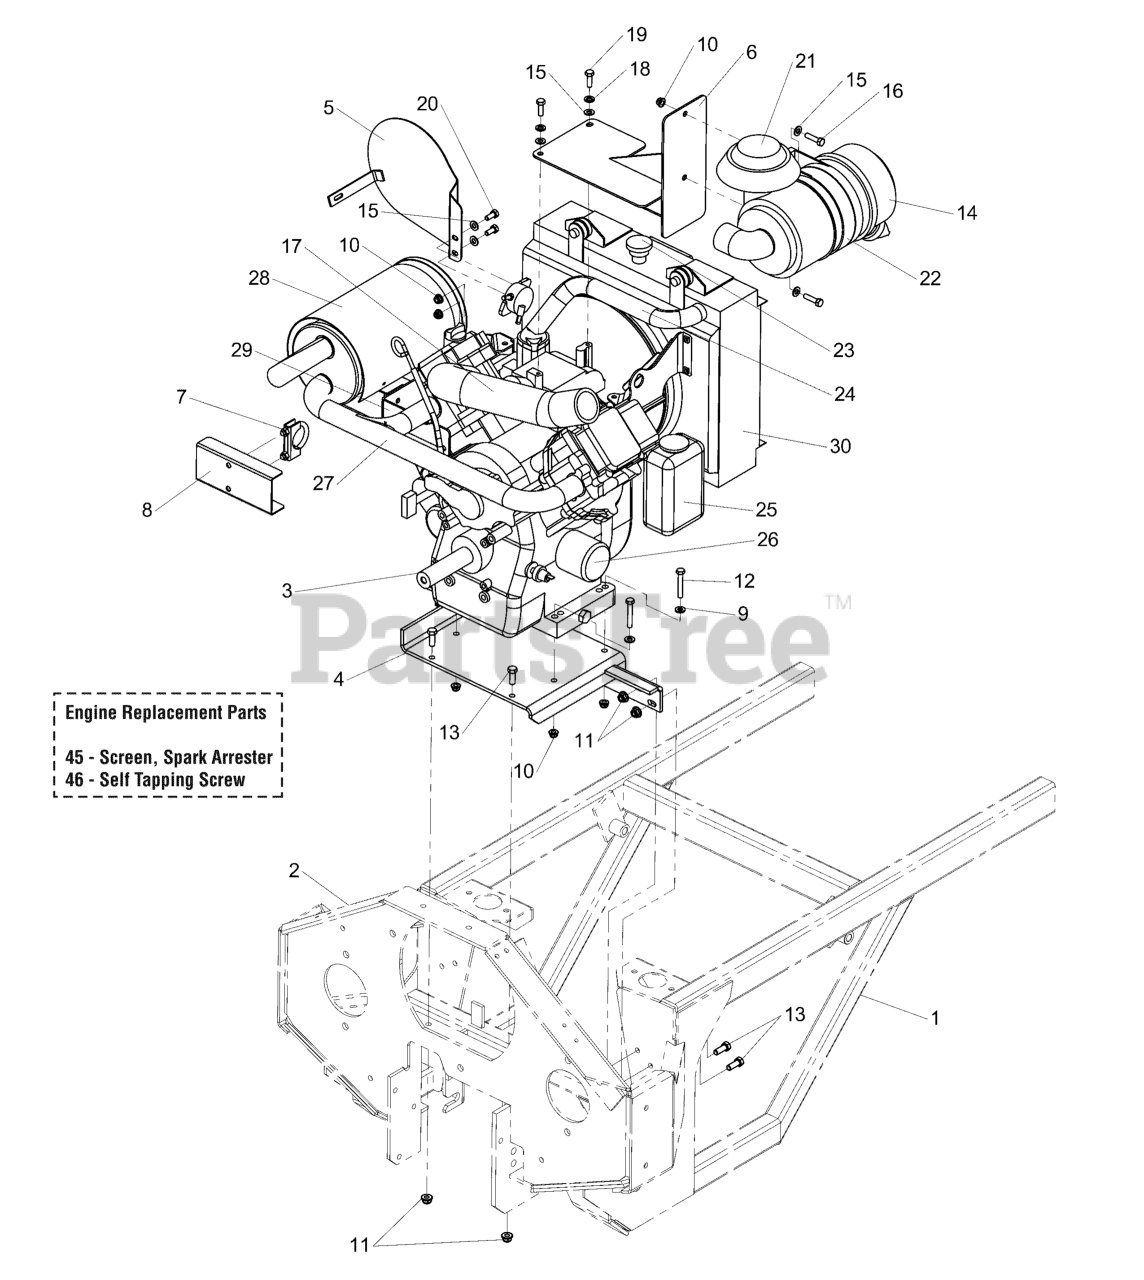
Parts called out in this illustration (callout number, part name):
1	MAIN FRAME
2	PUMP PLATE
4	ENGINE PLATE
5	MUFFLER GUARD
6	AIR CLEANER MOUNT
7	MUFFLER CLAMP, 1-1/2"
8	HEAT SHIELD
9	WASHER, 5/16" GD. 9 Flat
10	NUT, 5/16-18 Hex Nylock Flange
11	NUT, 3/8-16 Hex Nylock Flange
12	BOLT, 5/16-18 X 2"
13	BOLT, 3/8-16 X 1" GD5 CZ
14	AIR CLEANER ASSY
15	WASHER, 5/16" SAE
16	BOLT, 5/16-18 X 1-1/4"
17	AIR INTAKE HOSE
18	WASHER, 5/16 LOCK CZ
19	BOLT, M8-1.25 X 25MM GR 8.8
20	BOLT, 5/16-18 X 3/4 GD5
21	CAP, A/C RAIN
22	BRACKET, AIR CLEANER ASSY
23	PRESSURE CAP
24	UPPER WATER HOSE
25	OVERFLOW BOTTLE
26	FILTER, OIL, BRIGGS & STRATTON
27	EXHAUST MANIFOLD
28	MUFFLER
29	MUFFLER BRACKET
30	RADIATOR
31	AIR FILTER ELEMENT - Primary
32	AIR FILTER ELEMENT - Secondary
33	AIR INTAKE HOSE CLAMP
34	RADIATOR SCREEN
35	LOWER WATER HOSE - Pump to Tee
36	LOWER WATER HOSE TEE
37	LOWER WATER HOSE - Tee to Radiator
38	THERMOSTAT W/ GASKET
39	THERMOSTAT GASKET ONLY
40	OIL FILL CAP
41	DIPSTICK
42	FUEL PUMP
43	FILTER, FUEL
44	SENDER, WATER TEMPERATURE
45	SCREEN, ARRESTER
46	SCREW,SELF-TAP,#8-32 X 3/8,WASH HEX, CZ
47	TIE,SELF-LOCKING, 24"
